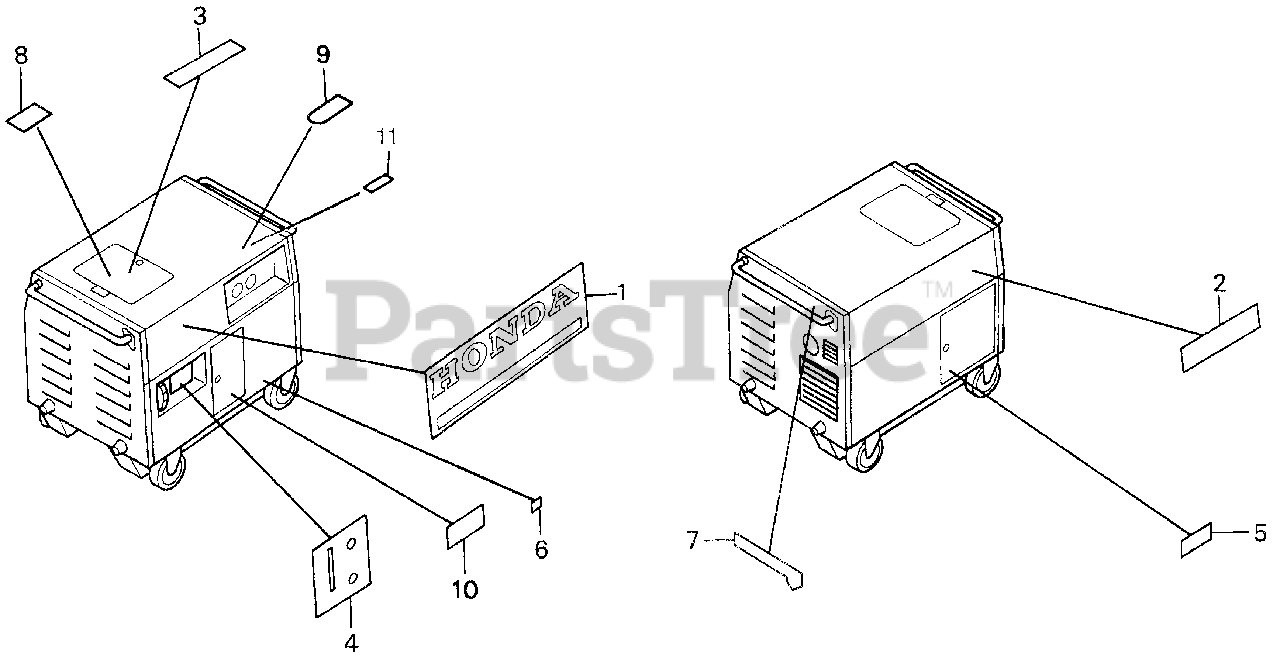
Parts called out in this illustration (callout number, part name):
1	EMBLEM, MAIN
2	PLATE, CAUTION
3	MARK, CAUTION (ENGLISH/FRENCH)(SPANISH)
4	MARK, ENGINE CONTROL
5	MARK, AIR CLEANER
6	MARK, GROUND
7	MARK, EX. CAUTION
8	MARK, CAUTION (CO)(ENGLISH/FRENCH)(SPANISH)
9	LABEL, CONNECT WARNING (ENGLISH)
10	MARK, OIL CAUTION
11	LABEL, RAIN WARNING (ENGLISH)
